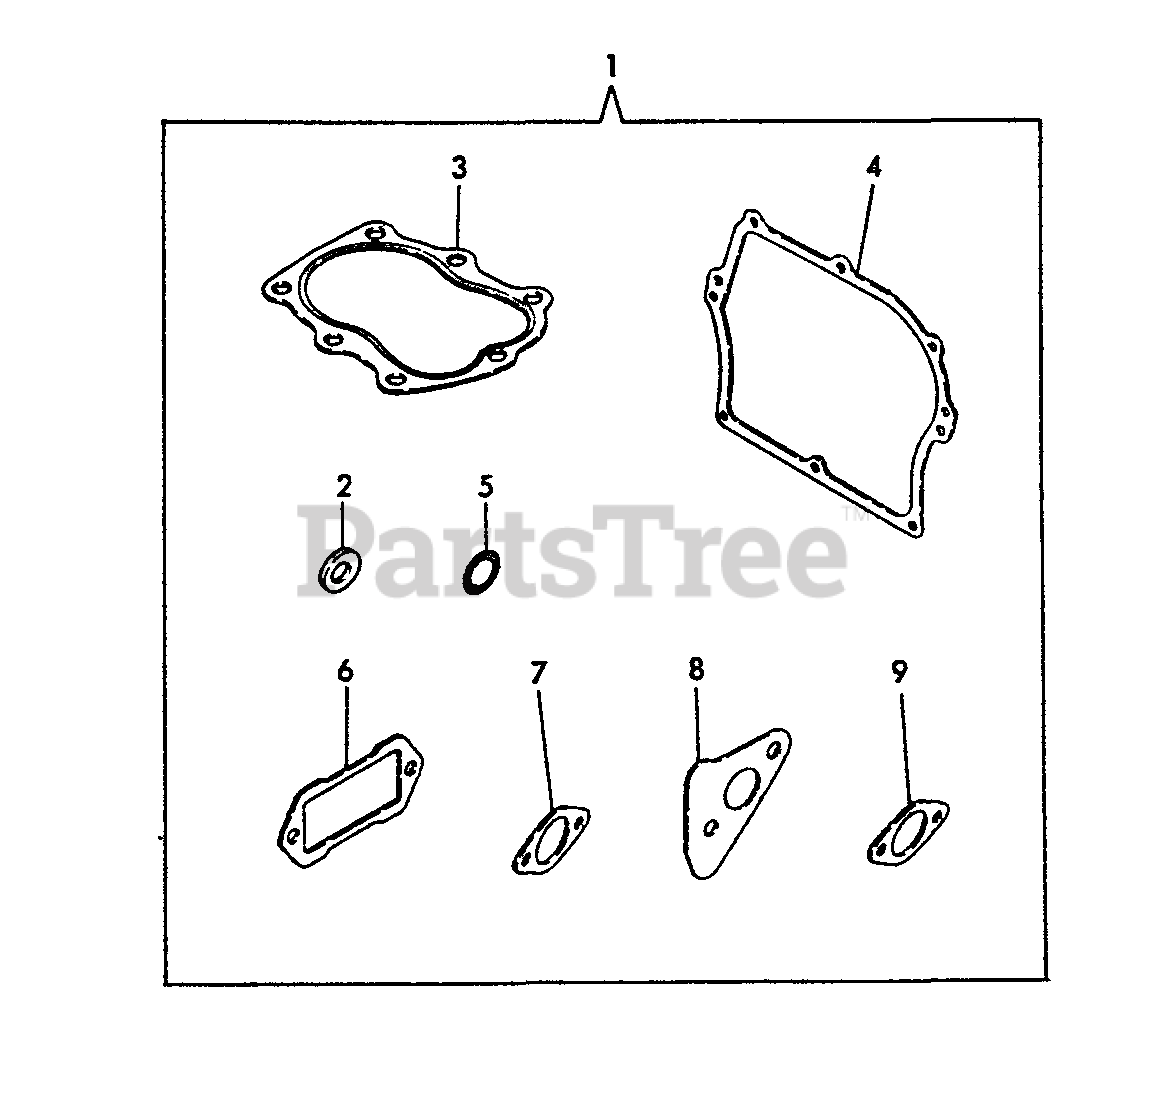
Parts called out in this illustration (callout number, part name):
1	GASKET KIT
2	GASKET
3	GASKET, CYLINDER
4	GASKET, SIDE COVER
5	O-RING 1A P-18.0
6	GASKET
7	GASKET, INTAKE
8	GASKET, EXHAUST
9	GASKET, EXHAUST
